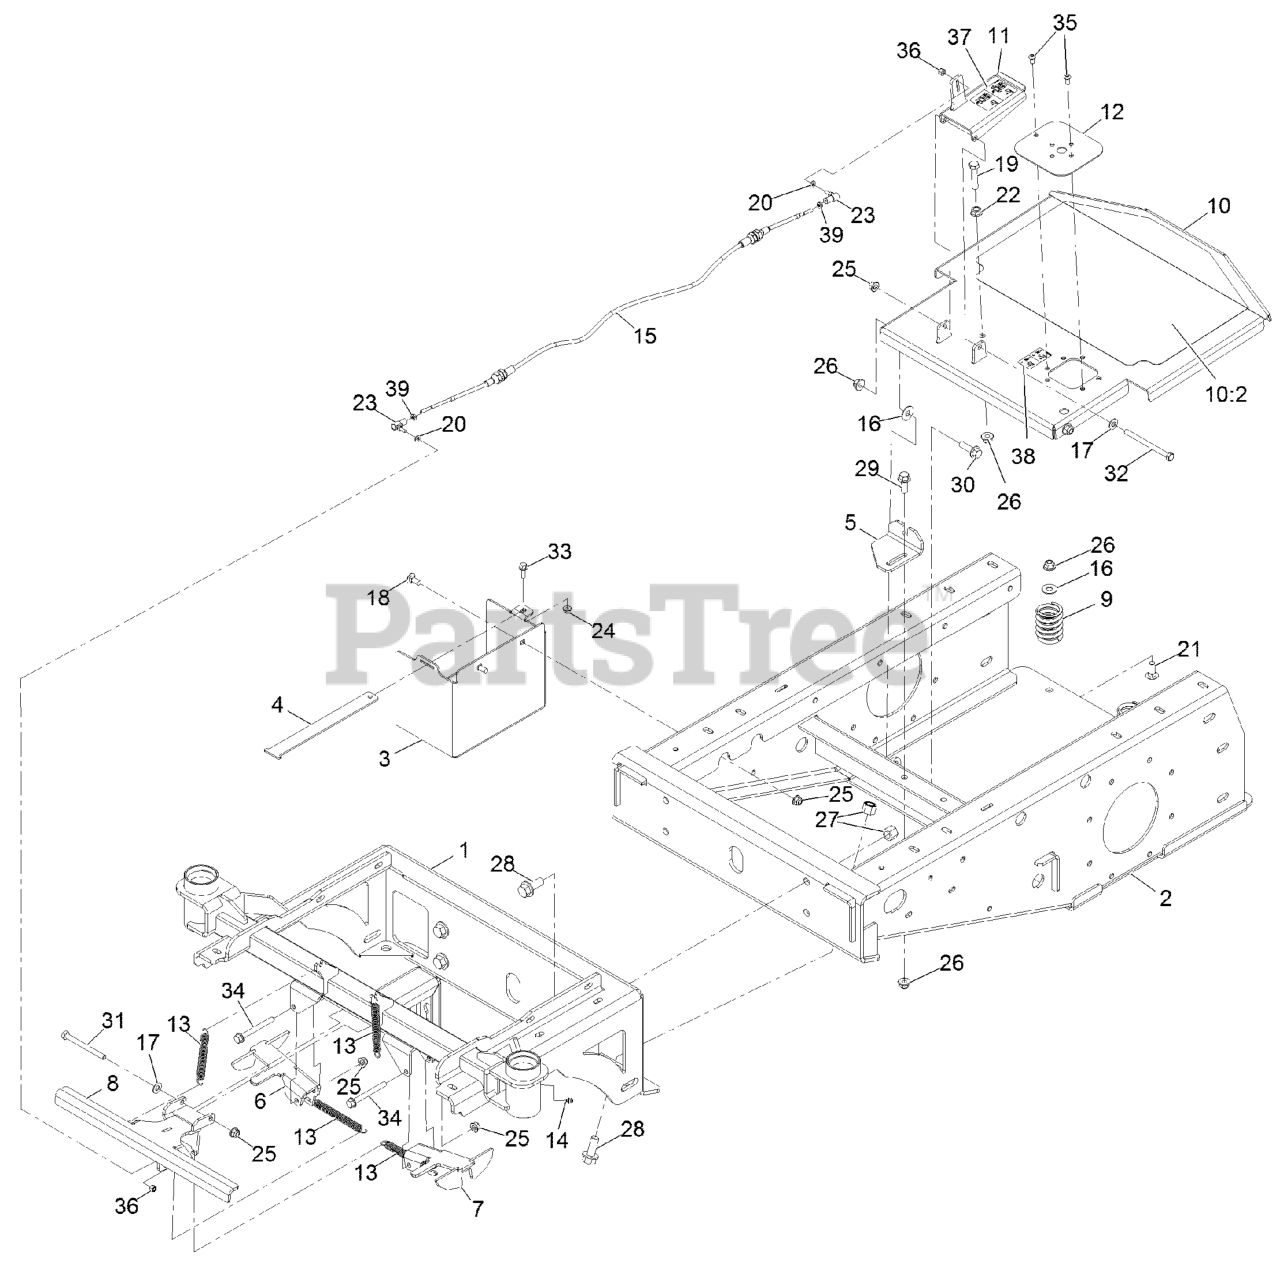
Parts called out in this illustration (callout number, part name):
1	Frame-Front
2	FRAME-REAR
3	Box-Battery
4	STRAP-BATTERY
5	Bracket, Lower Cable
6	Wing-Capture, Rt
7	Wing-Capture, Lt
8	Capture-Lcs
9	SPRING-COMPRESSION
10	Plate-Foot
10:2	PAD-GRIP
11	Pedal-Foot
12	Panel, Foot Switch
13	SPRING-EXTENSION
14	FITTING-GREASE, ZERK
15	CABLE-CASTER, LOCKING
16	WASHER-FLAT
18	SCREW-CARR
19	Screw-HH
20	WASHER-FLAT
21	SCREW-CARR
22	Nut-Hex Flange
23	BALL JOINT-SS
24	Nut-Hex Flange
25	Nut-Hex Flange
26	Nut-Hex Flange
27	Nut,1/2-13,NYL INS,ST/ST,18-8
28	SCREW-HHF
29	SCREW-HHF
30	SCREW-HHF
31	SCREW-HH
32	Screw-HH
33	Screw-HHF
34	SCREW-HHF
35	Screw-HSBH
36	Nut,NYL Lock,#10-32,ST/ST 18-8
37	Decal-Lock, Caster
38	Decal-Spray Foot Button
39	Nut,Hex Jam Mch Scr,10-32,Sst
